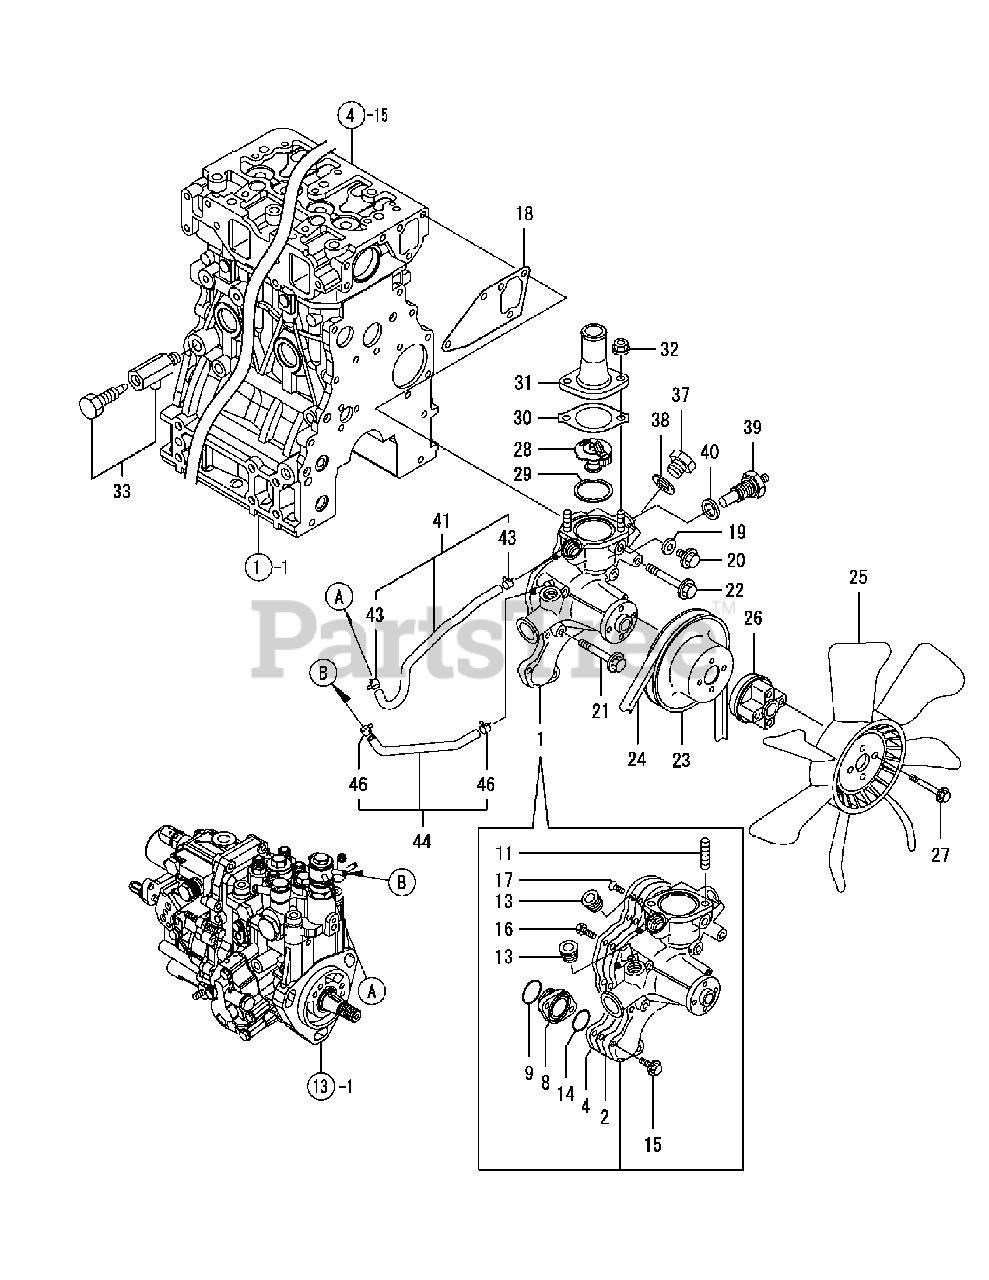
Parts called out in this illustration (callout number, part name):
1	PUMP ASSY, WATER
8	FLAGNE, C. W. PUMP
14	O-RING, 5 24031
15	BOLT M 6X 20 PLATED
17	SCREW M 6X 14
18	GASKET, WATER PUMP
19	GASKET 8, ROUND
20	BOLT M 8X 12 PLATED
21	BOLT M 8X 55 PLATED
22	BOLT M 8X 60 PLATED
23	V-PULLEY, WATER PUMP
27	BOLT M 6X 50 PLATED
29	GASKET, THERMOSTAT
31	COVER, THERMOSTAT
